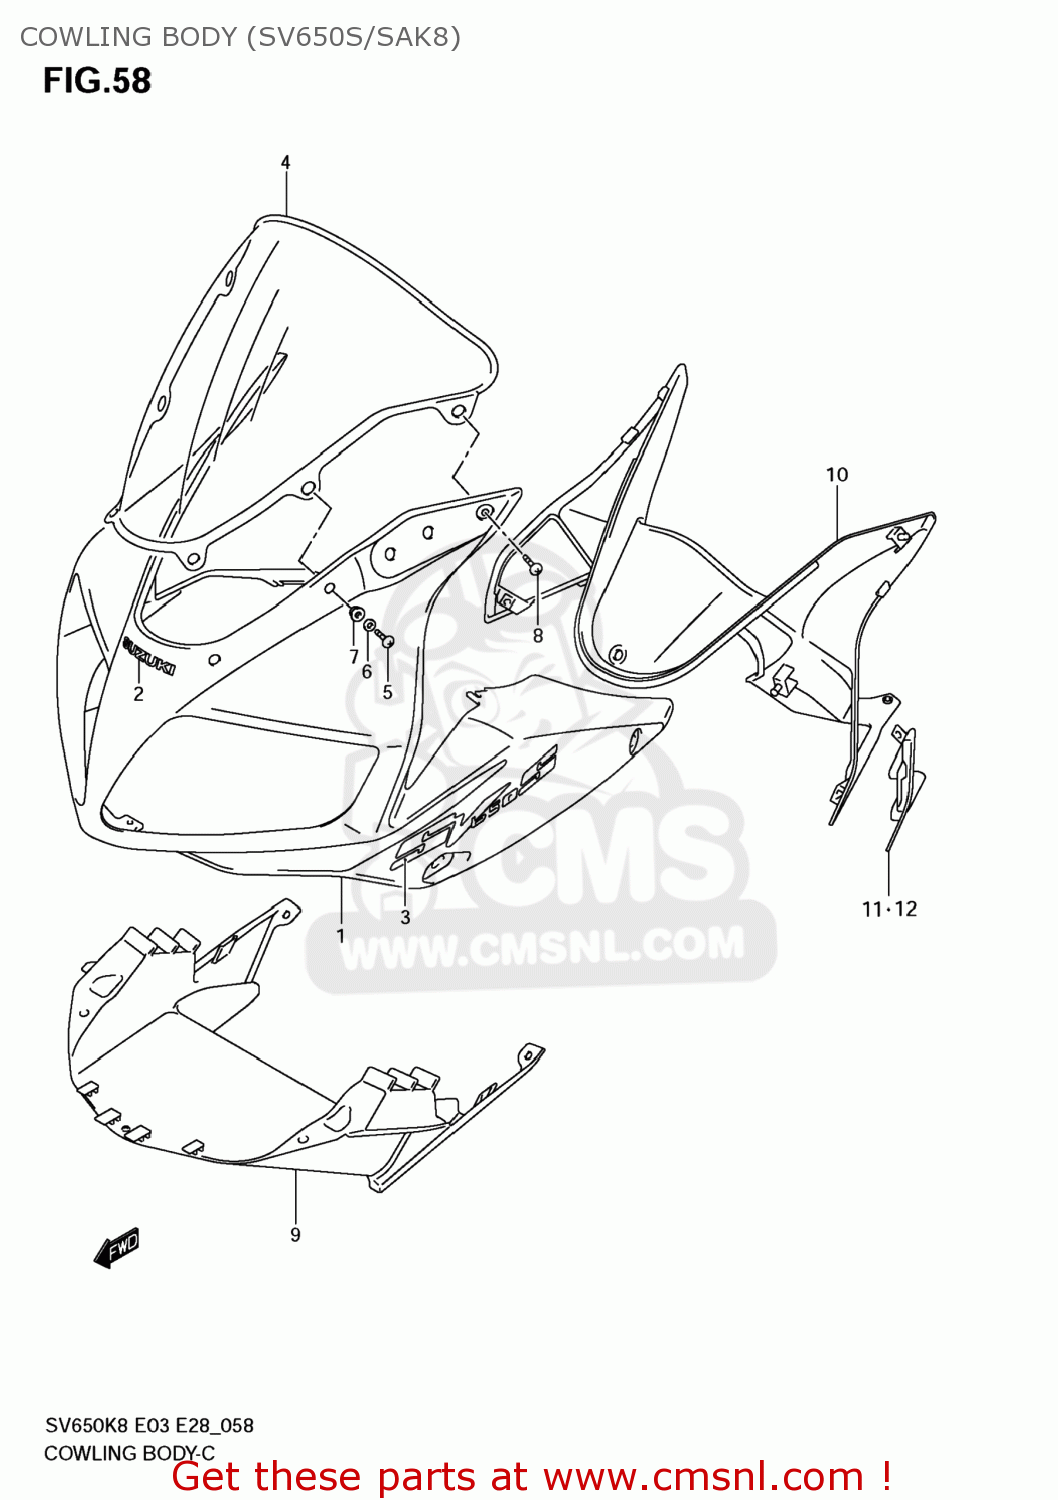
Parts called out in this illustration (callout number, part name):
1	COWLING ASSY,BODY
2	EMBLEM,SUZUKI
3	EMBLEM,BODY COWL
4	WINDSCREEN
5	SCREW(5X14)
6	WASHER
7	NUT
8	SCREW(5X16)
9	COVER,COWLING INNER
10	PANEL,METER
11	LID,METER PANEL,R
12	LID,METER PANEL,L
